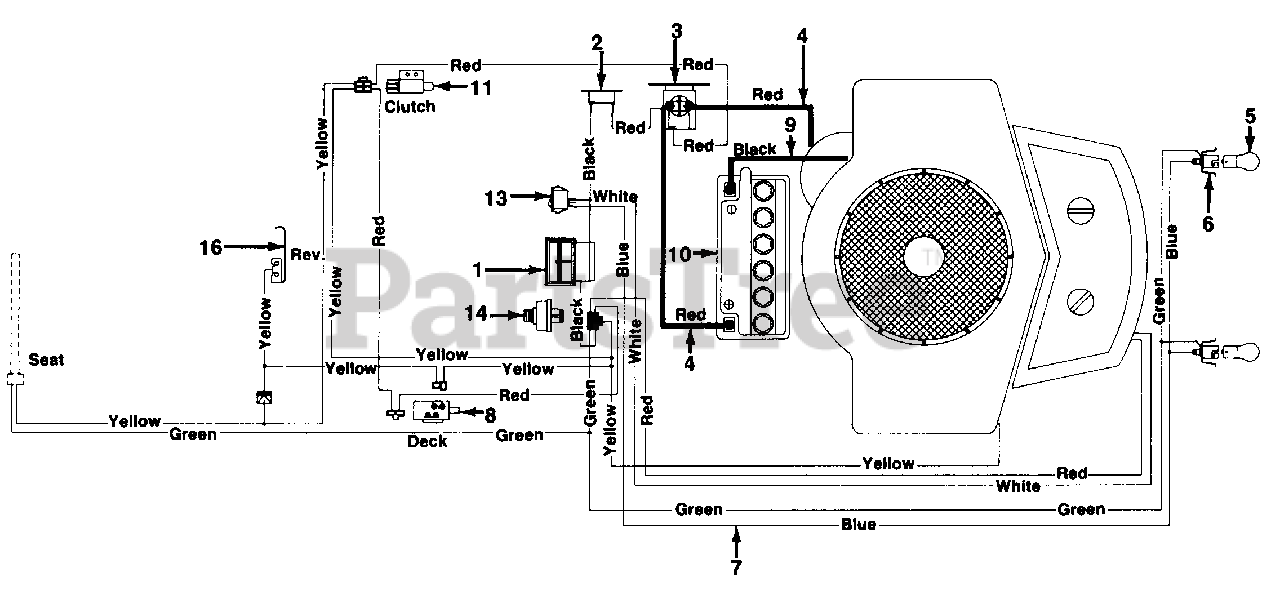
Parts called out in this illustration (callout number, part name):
1	Ammeter
2	Circuit Breaker
3	N Solenoid
4	Wire
5	Bulb
6	N Socket
7	N Wire Harness
8	Safety Switch
9	6 Ga. Black Wire
10	N Battery 12V
11	N Safety Switch
13	Light Switch
14	Ignition Switch
16	Spring Switch
